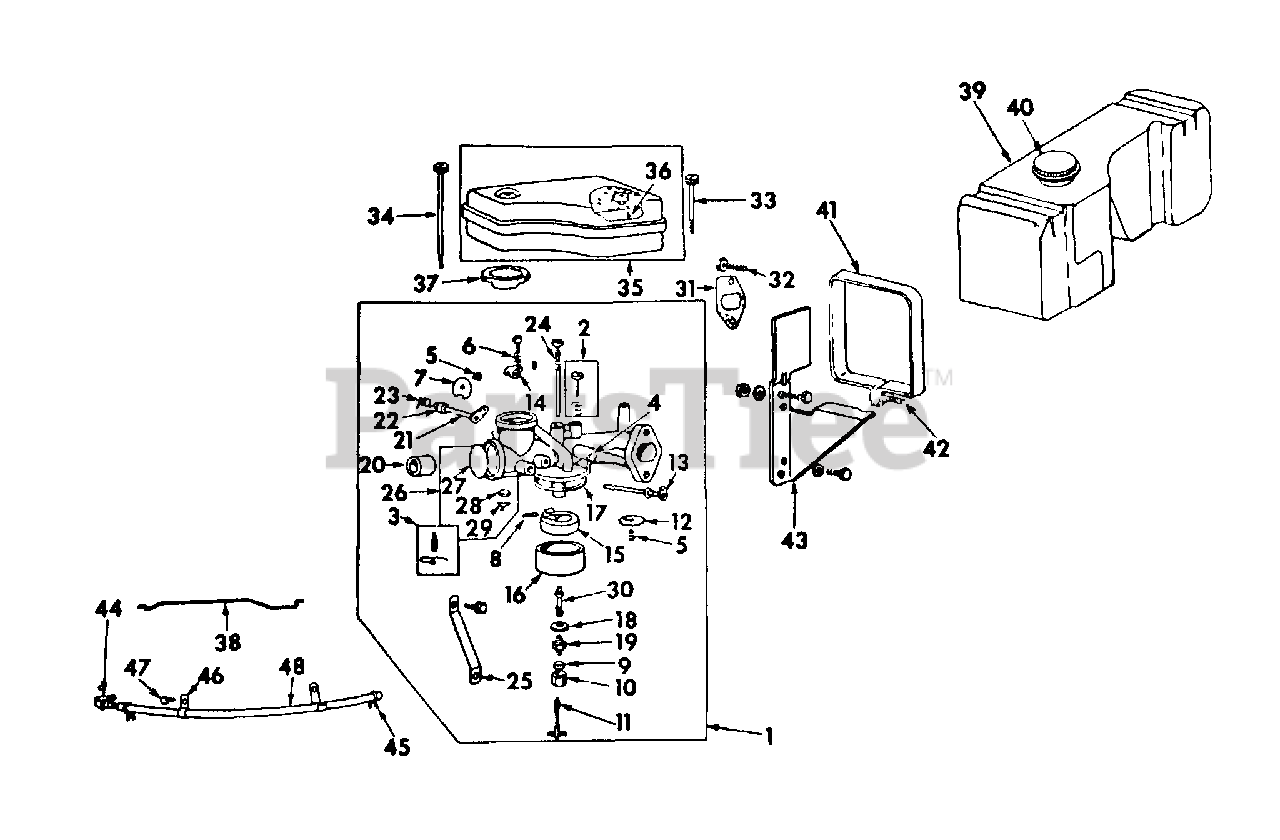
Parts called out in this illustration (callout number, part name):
1	CARBURETOR ASSY
2	VALVE ASSY, IDLE
3	VALVE ASSY, FLOAT
4	BUSHING, THROTTLE SHAFT
5	SCREW, CHOKE VALVE
6	SPRING, THROTTLE ADJ
7	VALVE, CHOKE
9	PACKING, NEEDLE JET
10	NUT, NEEDLE JET PACKING
11	VALVE, NEEDLE
12	VALVE, THROTTLE
13	SHAFT & LEVER ASSY, THROTTLE
14	STOP, THROTTLE
16	BLOW, FLOAT
17	GASKET, BOWL
18	WASHER, FLOAT BOWL
19	RETAINER, NEEDLE JET
21	SHAFT & LEVER ASSY, CHOKE
22	WASHER, CHOKE SHAFT FELT
23	SPRING, CHOKE RETURN
24	JET, IDLE NEEDLE
27	PLUG, EXPANSION
28	FILTER, DRAIN
31	GASKET, CARBURETOR
32	SCREW, CARBURETOR MTG
33	SCREW, AIR CLEANER
34	SCREW, AIR CLEANER
35	CLEANER ASSY, AIR
36	ELEMENT
37	GASKET, AIR CLEANER
39	TANK ASSY W/CAP, FUEL
40	CAP, FUEL TANK FILLER
41	STRAP, FUEL TANK FRONT
42	SCREW, 1/4-20 X 1-1/4 HEX-HD
43	BRACKET, FUEL TANK FRONT
44	CONNECTOR & SHUT-OFF FUEL
45	CLAMP, FUEL LINE HOSE
46	CLAMP, FUEL LINE HOSE
47	SCREW, 10-32 X 5/16 HEX-HD TAP
48	HOSE, FUEL LINE
